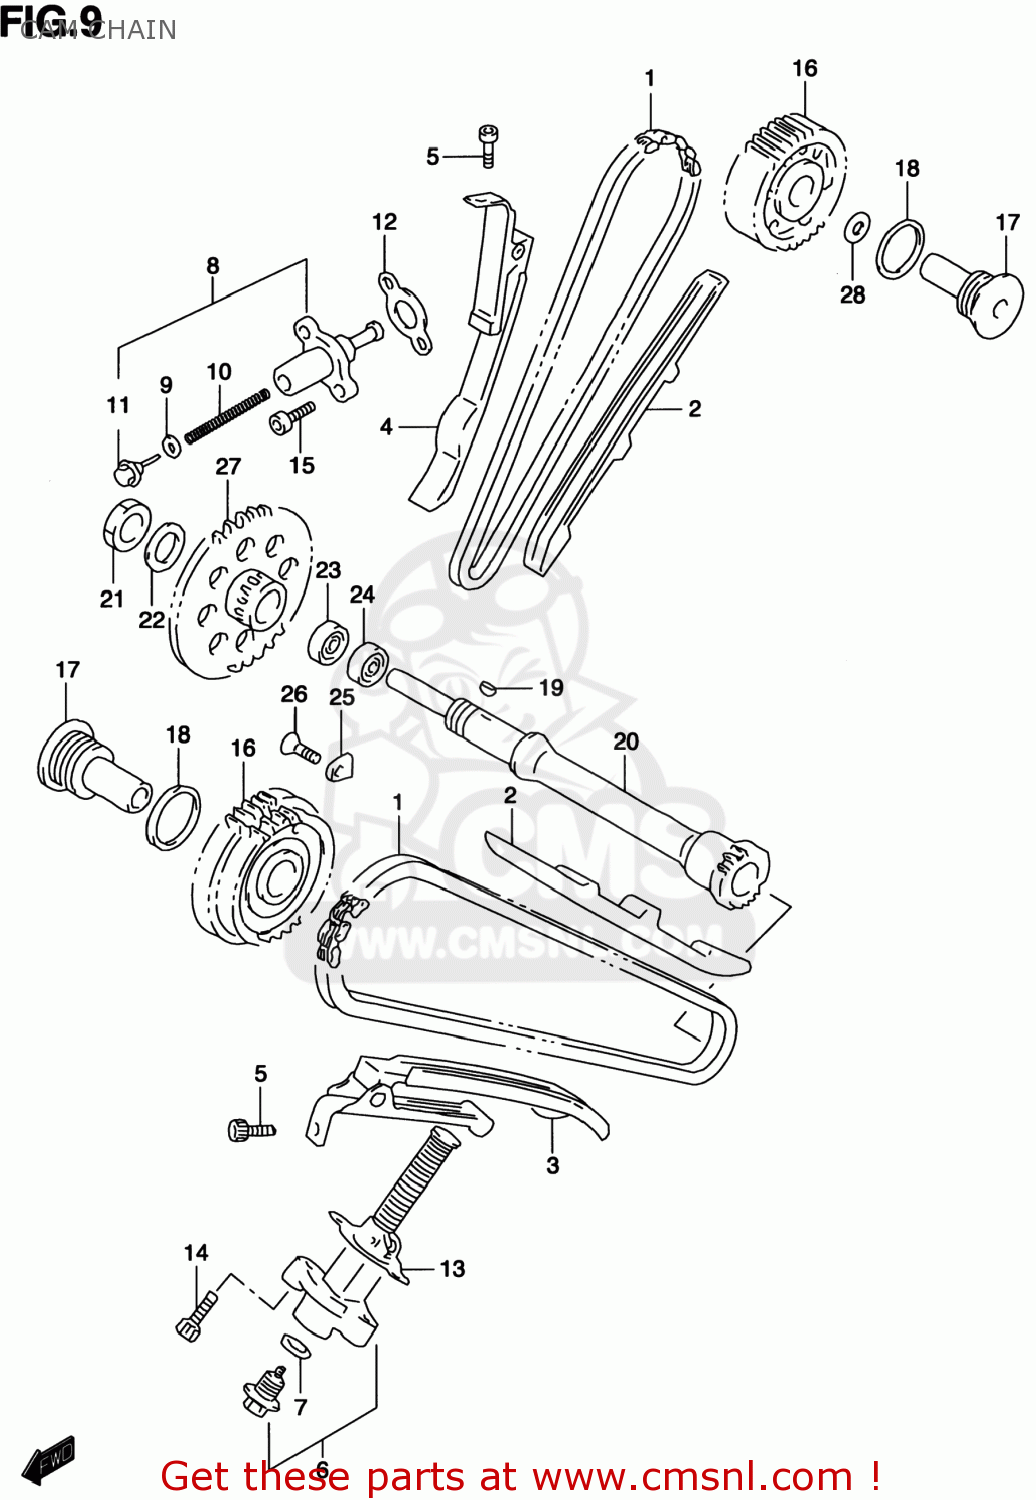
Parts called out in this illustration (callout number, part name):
1	CHAIN,CAMSHAFT DRIVE
2	GUIDE,CAM CHAIN
3	TENSIONER,CAM CHAIN FR
4	TENSIONER,CAM CHAIN RR
5	BOLT
6	ADJUSTER ASSY,RR TENSIONER
7	GASKET(12X21X2) (NAS)
8	ADJUSTER ASSY,TENSIONER
9	O RING
10	SPRING
11	PLUG,ADJUSTER
12	GASKET,TENSIONER ADJUSTER (NAS)
13	GASKET,TENSIONER ADJUSTER (NAS)
14	BOLT,CL.COVER
15	BOLT,CRKCASE,R
16	GEAR COMP,CAM CHAIN ID
17	SHAFT,IDLER NO.2
18	GASKET(26.5X30.5X1) (NAS)
19	KEY
20	SHAFT,IDLER
21	NUT
22	SHIM(16X26X1.5)
23	BEARING
24	BEARING
25	RETAINER,COUNTER BEARING,R
26	SCREW
27	SPROCKET,IDLER NO.1
28	SHIM(15X24X1)
